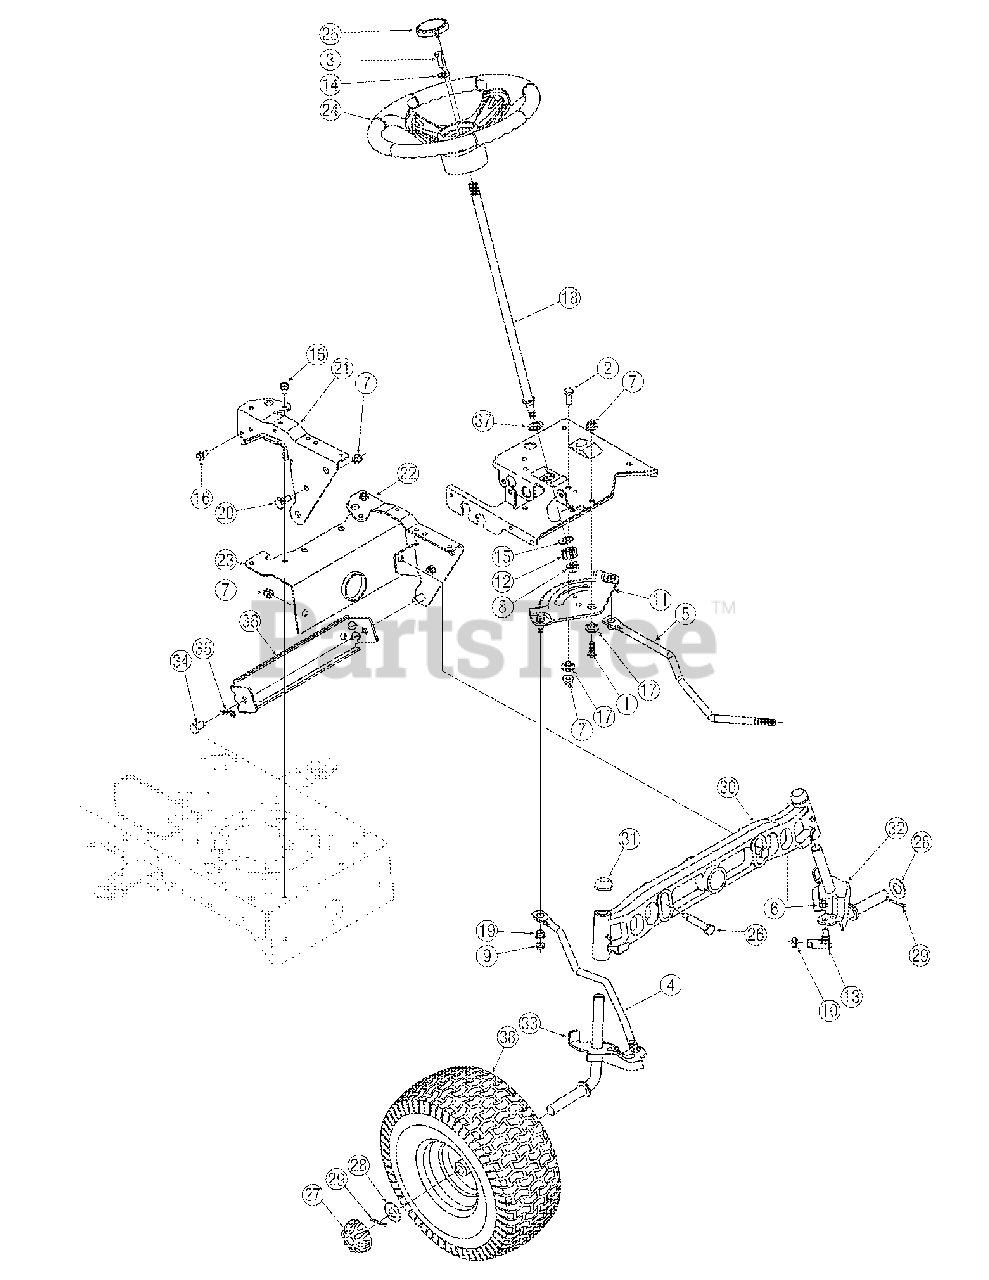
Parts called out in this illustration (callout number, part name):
1	Hex Screw, 3/8-16, 1.00, Gr5
2	Hex Screw, 3/8-16, 1.00, Gr5
3	Hex Screw, 5/16-18, 1.00, Gr5
4	Link, Drag, RH
5	Link, Drag, LH
6	Nut, Hex Lock, 3/8-24
7	Nut, Flange Lock, 3/8-16, Grf
8	Nut, Flange Lock, 7/16-20
9	Nut, Flange Lock, 5/16-18, Gr5
10	Nut, Jam, 7/16-20, Gr2
11	Gear, Steering, 11/90 Ratio
12	Gear, Pinion, Steering
13	Ball Joint, 7/16-20, Lock
14	Washer, Flat, .406 x .875
15	Washer, Flat, .51 x 1.12 x .06
16	Screw, 5/16-18, 0.750
17	Spacer, Shoulder, .38 x 1.00
18	Shaft, Steering, .625 OD x 24.25
19	Plastic Bushing .380 ID
20	Screw, Shoulder, .498 x .340
24	Steering Wheel
25	Steering Wheel Cap
26	Shoulder Screw, .5 x 2.2, 3 /18-16
27	Deluxe Hub Cap
28	Flat Washer, .78 x 1.589 x .06
29	Cotter Pin, 5/32 x 1.25
30	Cast Iron Pivot Bar
31	Push Cap
32	LH Axle Assembly, .750
33	RH Axle Assembly, .750
34	Pin, Clevis, .50 x .78
35	Cotter Pin, Internal, .080 x 1.5625
37	Hex Flange Bearing
